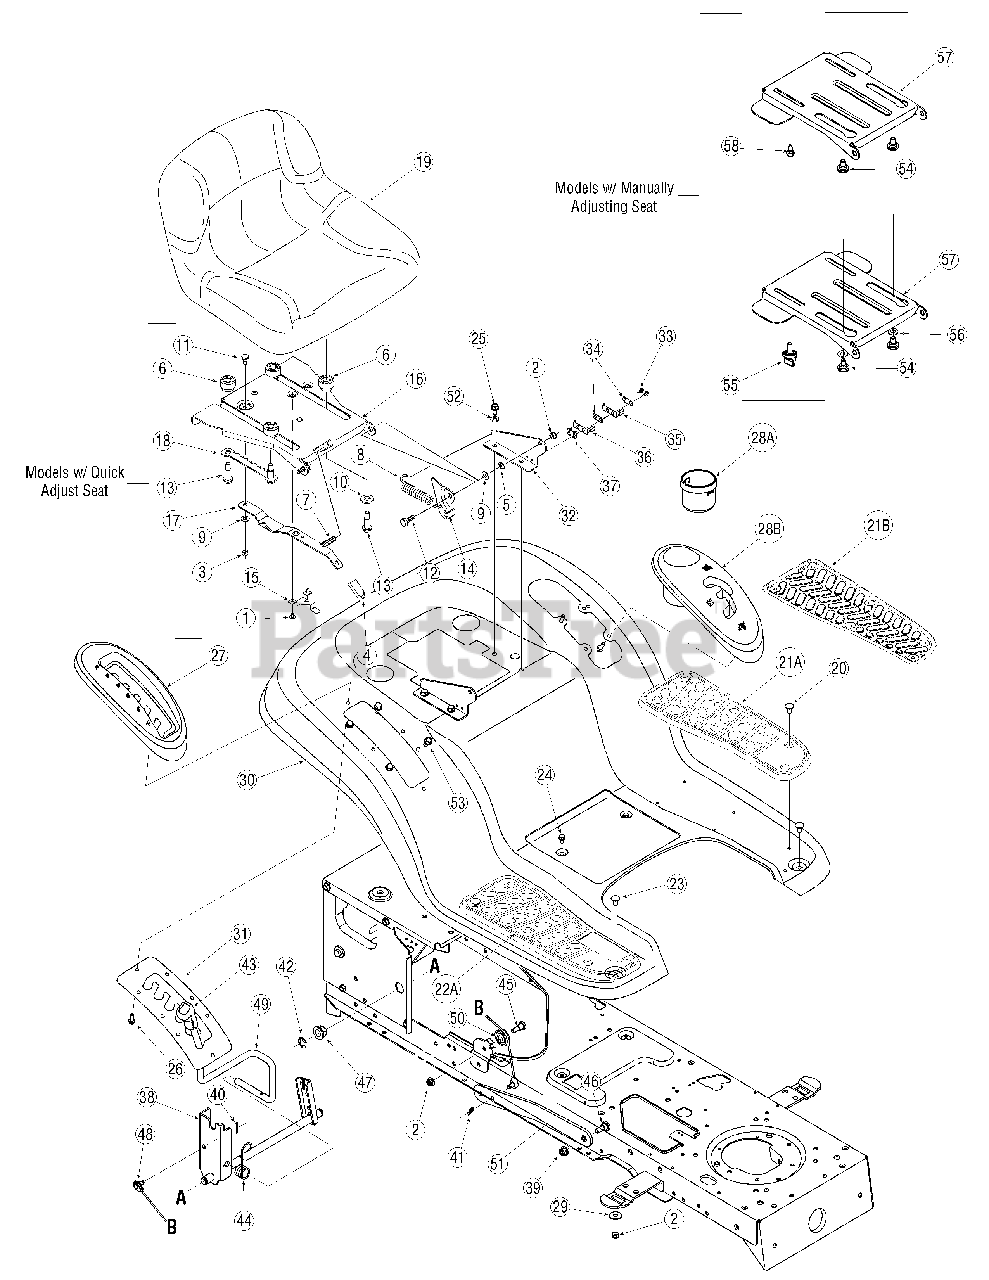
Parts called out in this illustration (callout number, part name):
1	Screw, #10-16 x.375 (if equipped)
2	Nut, Flange Lock, 5/16-18, GrF
3	Nut, Flange Lock, 1/4-20 (if equipped)
4	Seat Adjuster Grip (if equipped)
5	Nut, Speed, .3125 ID (if equipped)
6	Spacer (if equipped)
7	Compression Spring, .41 x 1.5 (if equipped)
8	Spring, Extension, .84 Dia. X 4.6
9	Wash, Flat, .344 x.688 x.065 (if equipped)
10	Wash, Flat, .531x 1.062 x.134 (if equipped)
11	Screw, Shld, .340 x.285, 1/4-20 (if equipped)
12	Screw, Shoulder, .437 x.268
13	Screw, Should, .50 x.925, 3/8-16 (if equipped)
14	Seat Bracket, Lift
15	Seat Stop (if equipped)
18	Seat Adjustment Selector (if equipped)
19	Medium Back Seat
20	Ratchet Clip
23	Bolt, Carriage, 5/16-18, .75,
24	Screw, 1/4-20, 0.500
25	Screw, 5/16-18, 0.625
26	Screw, 1/4-15, 0.750 (if equipped)
27	Cover, Lift Lever (if equipped)
29	Washer, Flat, .344 x 1.0 x .063
33	Screw, #8-18 x.50
34	Plate, Insulator
35	Spring Switch, Outer
36	Spring Switch, Inner
37	Plate, Insulator Boss
39	Nut, Flange Lock, 3/8-16, GrF
40	Pin, Cotter, .072 Dia. x 1.13
41	Pin, Cotter, 3/32, 1.0
42	Ring, E Type, .625 Dia.
43	Grip, Handle, 1/2
44	Spring, Torsion
45	Screw, 5/16-18 x.620 Gr2
46	Scr., Shldr, .625 x.165, (42" Deck)
46	Screw, Shld, .50 x.27, (46" Deck)
47	Bearing, Hex Flange
48	Cable, Lift, 16.16
49	Handle, Lift
50	Pulley, Roller
52	Lock Washer, 5/16
53	Scr5/16-18 x.750 (Model (Model X605H)
53	Screw, 5/16-12
54	Shoulder Screw
55	Knob, 3/8-16 (if equipped)
56	Flat Washer, .406 x .875 (if equipped)
58	Hex Head Washer Screw, 3/8-16 (if equipped)
